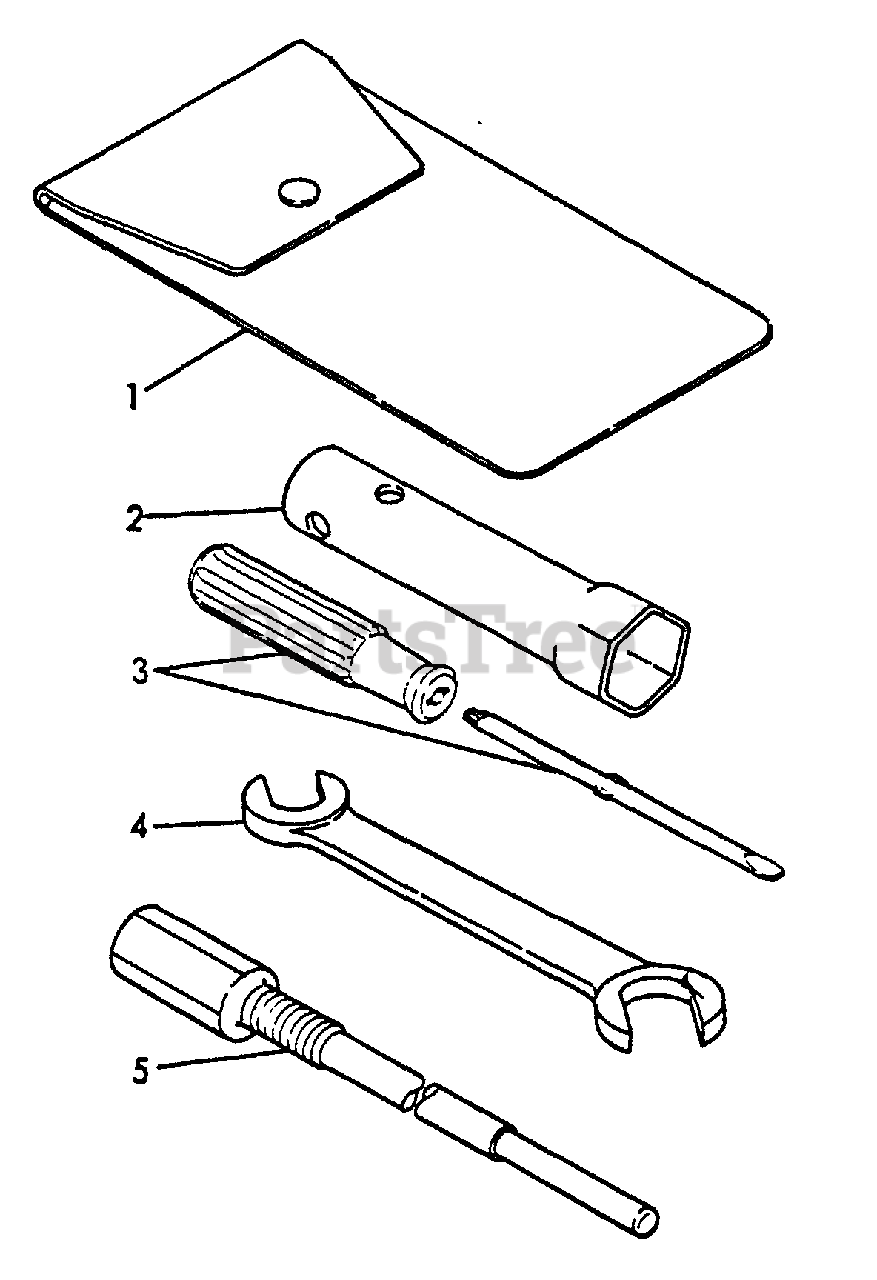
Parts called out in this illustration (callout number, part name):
1	BAG, TOOL
2	SOCKET WRENCH - 21mm
3	SCREWDRIVER
4	SPANNER - 10X12mm
5	REMOVER, ROTOR
